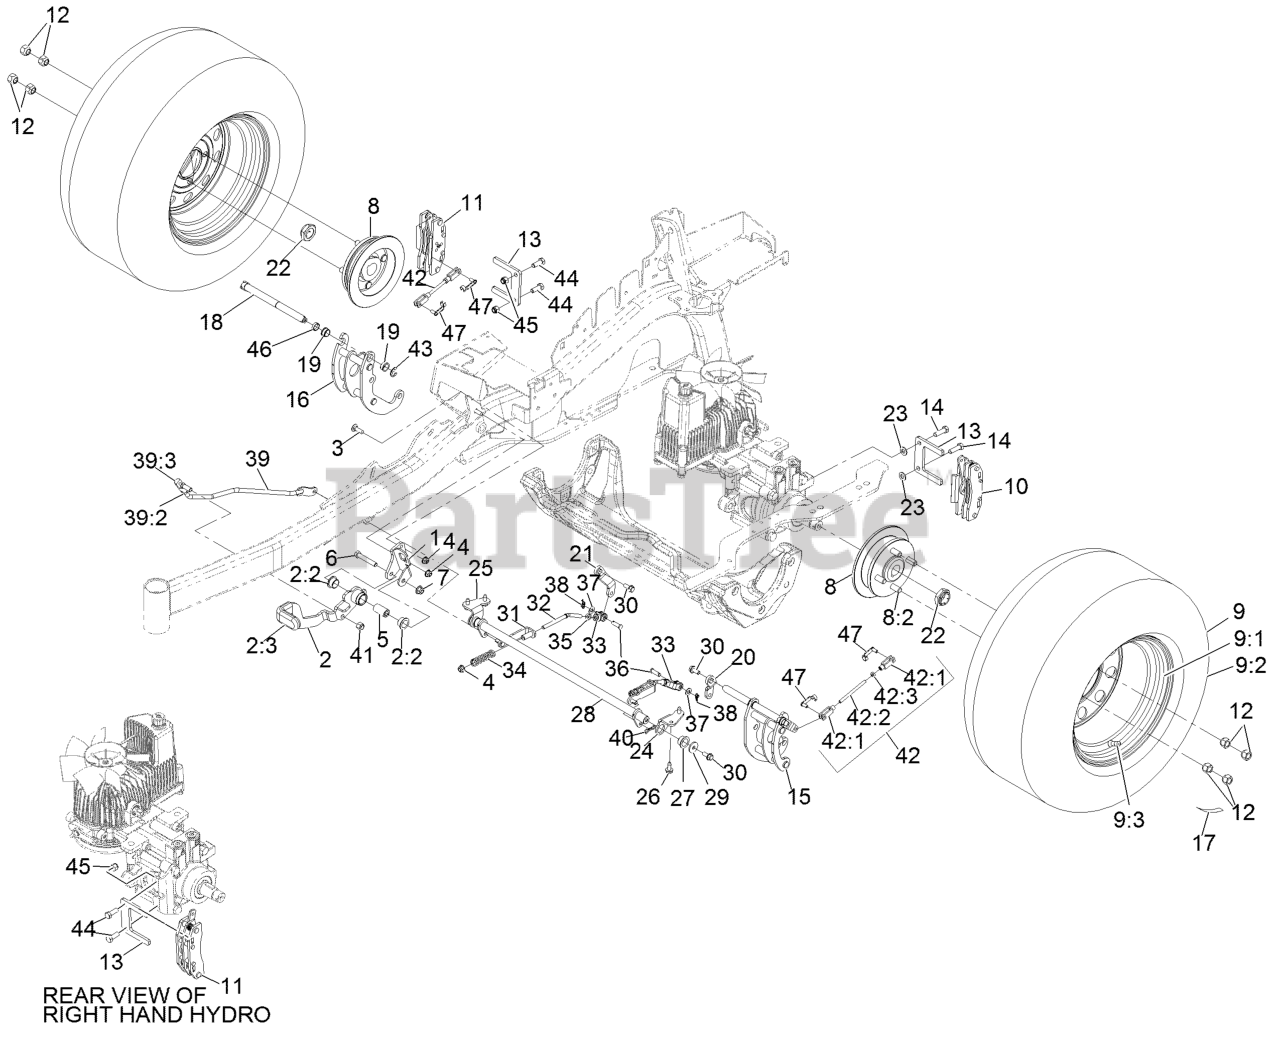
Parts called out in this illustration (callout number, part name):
1	BRACKET-MOUNT
2	BRAKE LEVER ASM W/ GRIP
2:2	BUSHING-FLANGE
2:3	GRIP-LEVER
3	BOLT-CARR
4	NUT-HF, NI
5	HANDLE-PIVOT, BRAKE
6	SCREW-HH
7	NUT-HF, NI
8	WHEEL HUB ASM
8:2	STUD-WHEEL
9	ASM-WHEEL AND TIRE
9:1	ASM-RIM 60
9:2	TIRE-DRIVE
9:3	Stem-Valve
10	CALIPER-BRAKE
11	CALIPER-BRAKE, RH
12	NUT-LUG
13	PLATE-MOUNT, BRAKE
14	SCREW-LOCK, PATCH
15	MOUNT-BELLCRANK, LH
16	MOUNT-BELLCRANK, RH
17	DECAL-TORQUE, WHEEL HUB LUG
18	BELLCRANK
19	BUSHING
20	ARM-INNER, LH
21	ARM-INNER, RH
22	LOCKNUT
23	WASHER-FLAT
24	MOUNT-PIVOT, LH
25	MOUNT-PIVOT, RH
26	Screw-HWH 5/16-18 X 3/4 Tf
27	BUSHING-FLANGE
28	SHAFT-CROSS
29	WASHER-FLAT
30	SCREW-HHF
31	BRACKET-L
32	LINKAGE-MID
33	YOKE-OFFSET
34	SPRING-COMPRESSION
35	NUT-JAM
36	PIN-CLEVIS
37	WASHER-PLAIN
38	PIN-COTTER, LOCKING
39	FRONT LINKAGE ASM
39:2	END-TIE ROD, RH
39:3	NUT-HJ
40	PIN-COTTER, LOCKING
41	NUT-LOCK
42	REAR LINKAGE ASM
42:3	NUT-JAM
44	SCREW-HH
45	NUT-LOCK, NI
47	PIN-CLEVIS, SPRING
